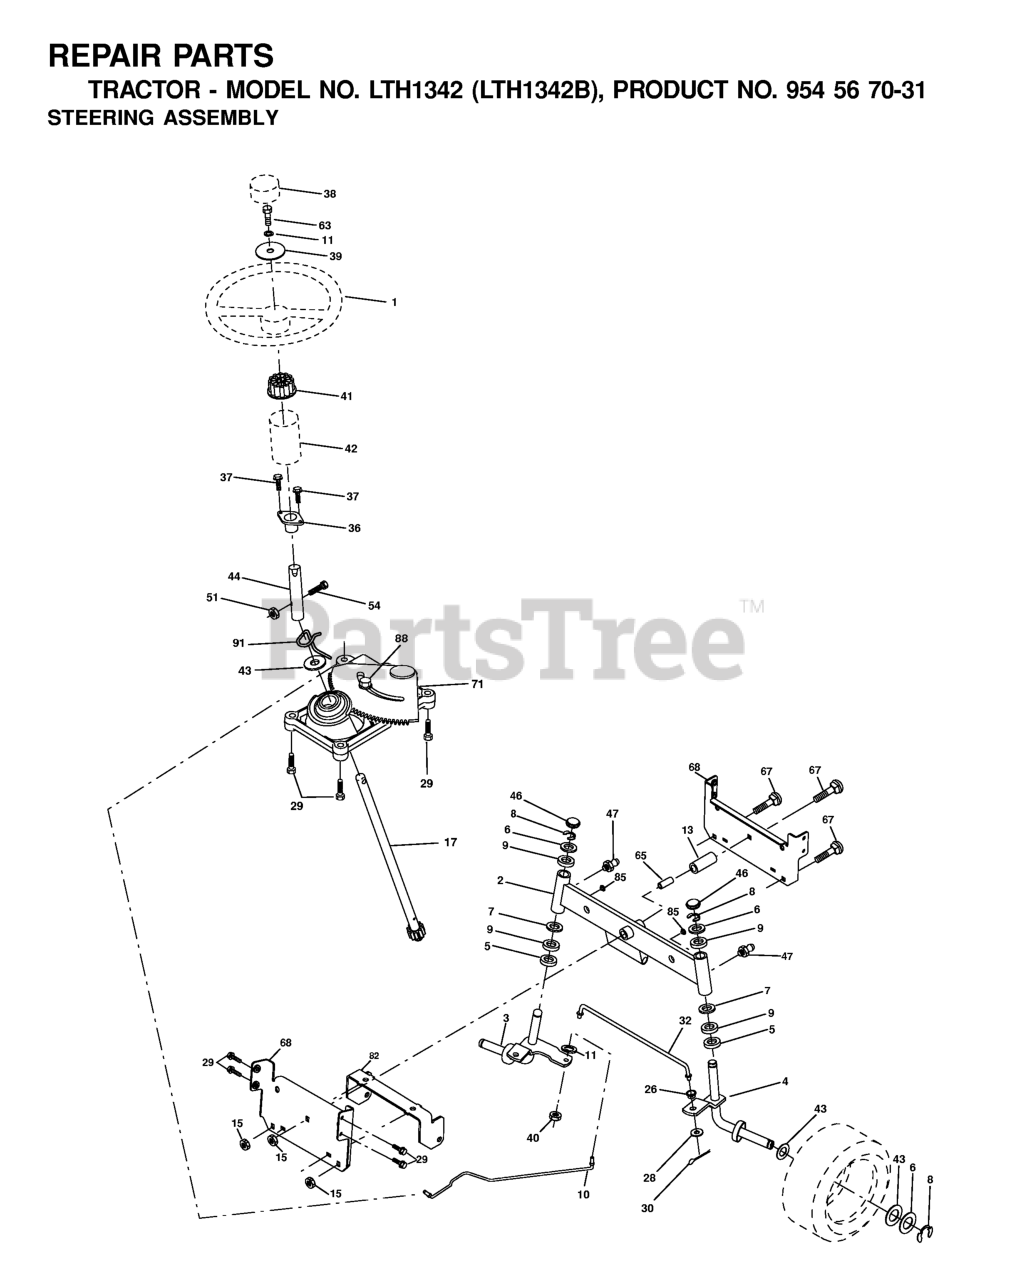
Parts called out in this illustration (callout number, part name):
1	STEERING WHEEL
2	AXLE ASSY
3	SPINDLE.ASM.LH.15"TIRES
4	SPINDLE.ASM.RH.15"TIRES
5	THRUST WASHER
9	BRNG T
10	DRAGLINK.15".TIRES.2001
11	WASHER, LOCK 3/8
13	TUBE, PIVOT AXLE
15	NUT
17	SHAFT ASM
26	BUSHING.DRAGLINK (2 2)
28	WASHER
29	SCREW 3/8-16X3/4
30	COTTER PIN
32	TIE ROD
36	BUSHING, STEERING
37	SCREW.TT.#10-32X.5.3/8.FLANGE
38	INSERT,STR WHEEL
39	WASHER 13/32 X 2-3/8 X 12GA
40	GRIPCO NUT
41	ADAPTER LT
42	BOOT STEERING
44	EXT SHAFT STEERING
46	CAP.SPINDLE.BLACK
47	ZERK M
51	NUT.71038.31-18.HEX.NYLOCK
54	BOLT.5/16-18X1-1/4 FULL.THREAD
65	SPACER BRACE AXLE
67	BOLT
68	BRACE.AXLE.15"TIRES
71	STEERING ASM
82	BRACKET
85	FASTENER.XMAS.TREE
88	BOLT, SHOULDER 7/16-20
91	CLIP.STEERING
